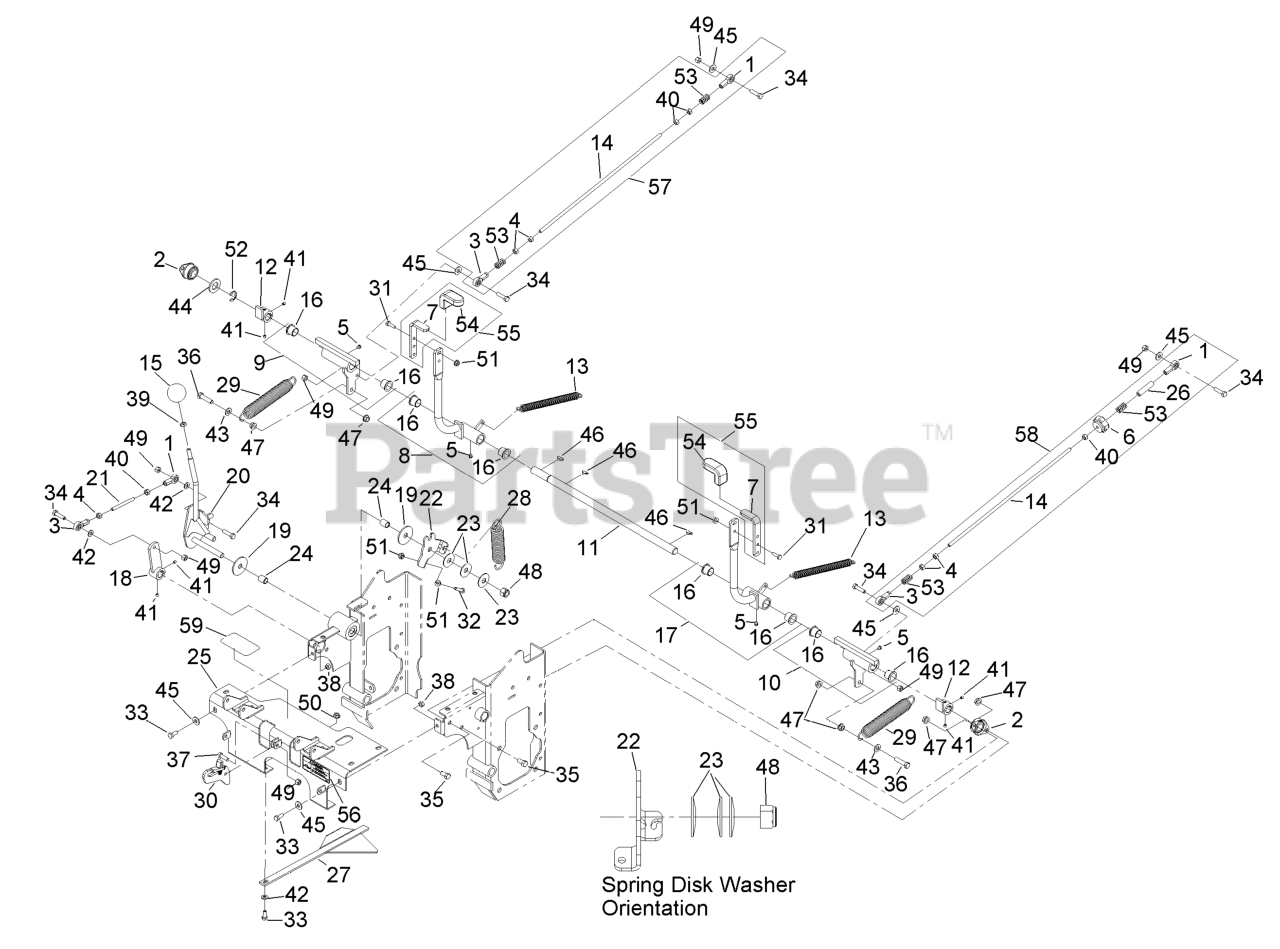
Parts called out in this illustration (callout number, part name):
1	BALLJOINT-RH
2	BEARING-FLANGE, SIDE
3	BALLJOINT-LH
6	KNOB-TRACKING
7	ASM,HANDLE W/GRIP
8	ASM,STEERING LEVER RH W/B
9	ASM,ACTUATOR RH W/BEARING
10	ASM,ACTUATOR LH W/BEARING
11	SHAFT,SPEED CONTROL
12	WLD,HUB SPEED CONTROL
13	SPRING,EXTENSION
14	LINKAGE,ROD LH STEERING (
15	KNOB-BALL, SPEED CONTROL
16	BEARING-FLANGE, IGLIDE
17	ASM,STEERING LEVER LH W/B
18	WLD,CONTROL ARM (PLATED)
19	DISC-FRICTION
20	WLD,SPEED CONTROL LEVER(P
21	ROD,THREADED CONTROL LINK
22	PLATE,SPEED CONTROL FRICT
23	WASHER-DISC, SPRING
24	BEARING,PLASTIC 1/2"
25	Asm, Console W/Decals
27	GUIDE-PLENUM
28	SPRING,EXTENSION (PLATED)
29	SPRING-EXTENSION
31	SCREW-HH
32	SCREW-HH
33	SCREW-HH
34	SCREW-HH
35	SCREW-HH
36	SCREW-HH
37	SCREW-HH
38	NUT-HEX
39	NUT-JAM
40	NUT-HEX
41	SCREW-SET, HSH
42	WASHER-PLAIN
43	WASHER-FLAT
44	WASHER-FLAT
45	WASHER-FLAT
46	KEY-WOODRUFF
47	NUT-HHF, WHIZ
48	NUT-HEX
49	NUT-LOCK, NI
53	SPRING-COMPRESSION
54	GRIP-HANDLE, STEERING
55	ASM,HANDLE W/GRIP
56	DECAL-DRIVELINE
57	ASM,RH PUMP LINKAGE
58	ASM,LH PUMP LINKAGE
59	DECAL,WHEEL MOTOR RELEASE
